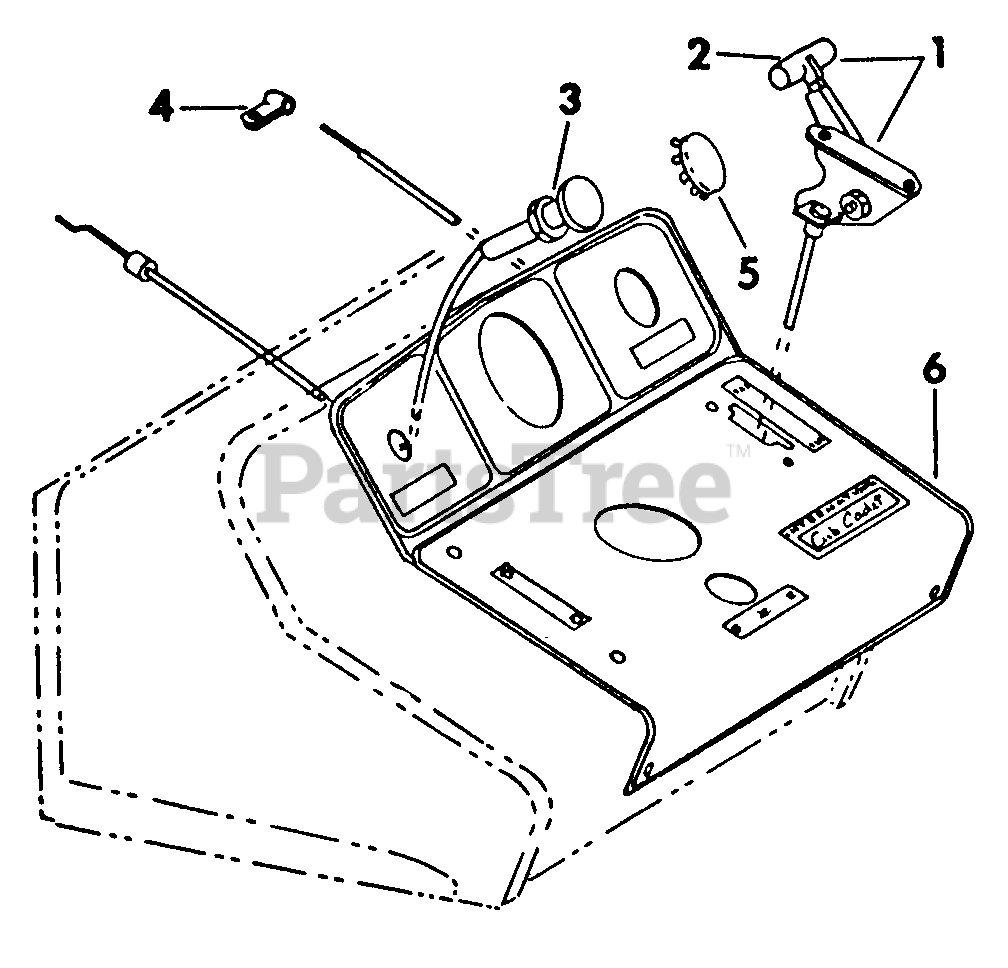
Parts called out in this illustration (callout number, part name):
1	Control, Throttle
2	Knob, Throttle Control
3	Cable, Choke
4	Clip, Throttle Cable Retaining
5	Plug, 29/32 Crb Button
6	Product Graphic, Instrument Panel
